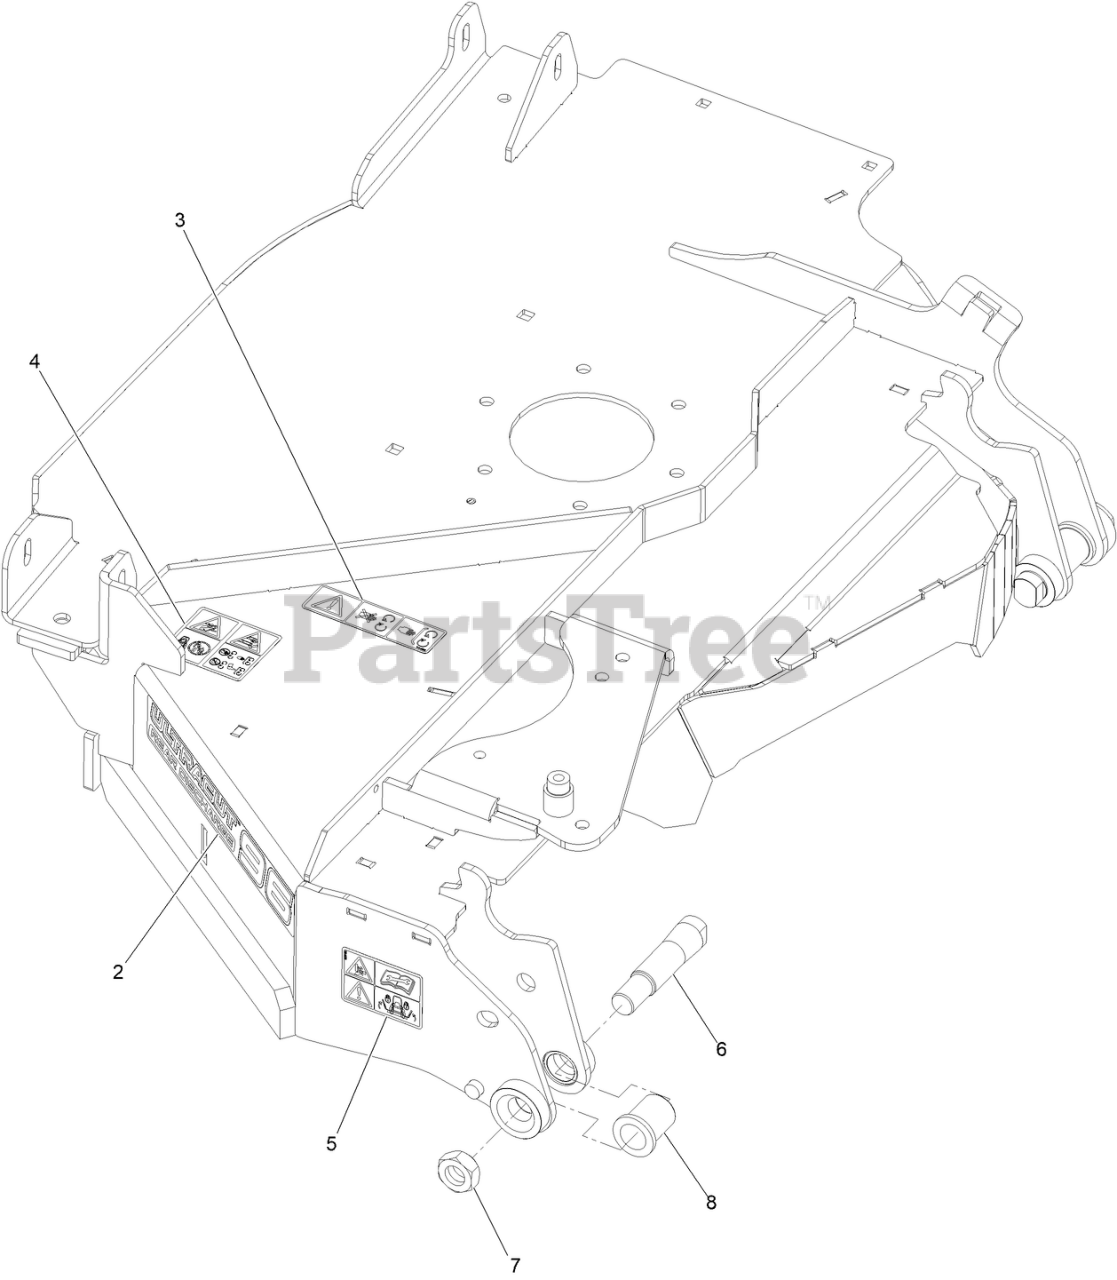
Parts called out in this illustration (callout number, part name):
2	DECAL-ULTRACUT 96-RD
3	DECAL-COVER, MISSING
4	DECAL-DANGER, THROWN OBJECT
5	DECAL-WARNING, PINCH POIN
6	BOLT-PIVOT PIN
7	NUT-LUG
8	BUSHING-FLANGED
